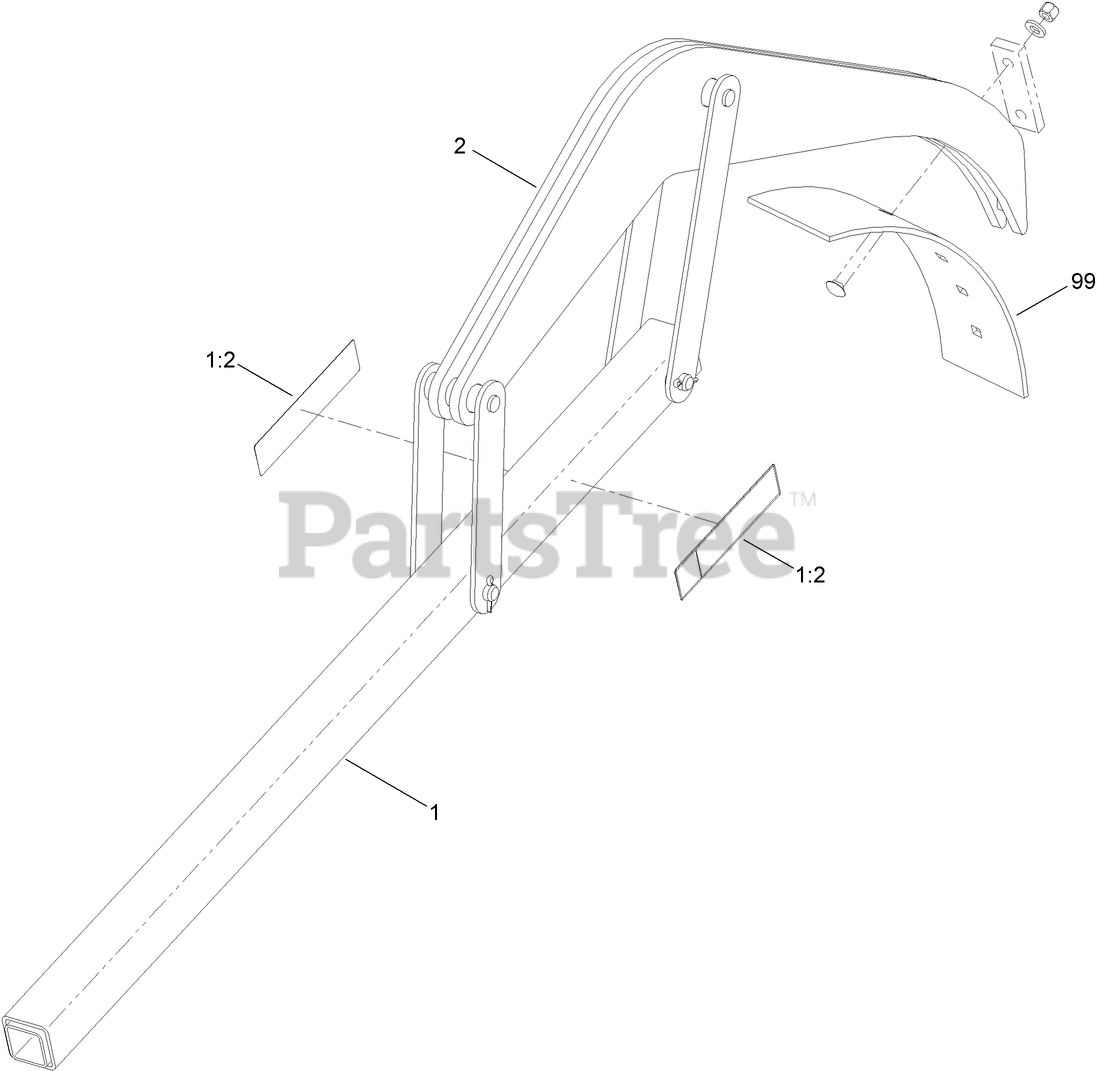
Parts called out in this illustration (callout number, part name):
1	CRUMBER TUBE ASM
1:2	DECAL-DANGER, ENTANGLEMENT
2	I / BASIC CRUMBER ASM
99	BLADE-MANUAL CRUMBER, 6 INCH CUT
99	BLADE-MANUAL CRUMBER, 8 INCH CUT
